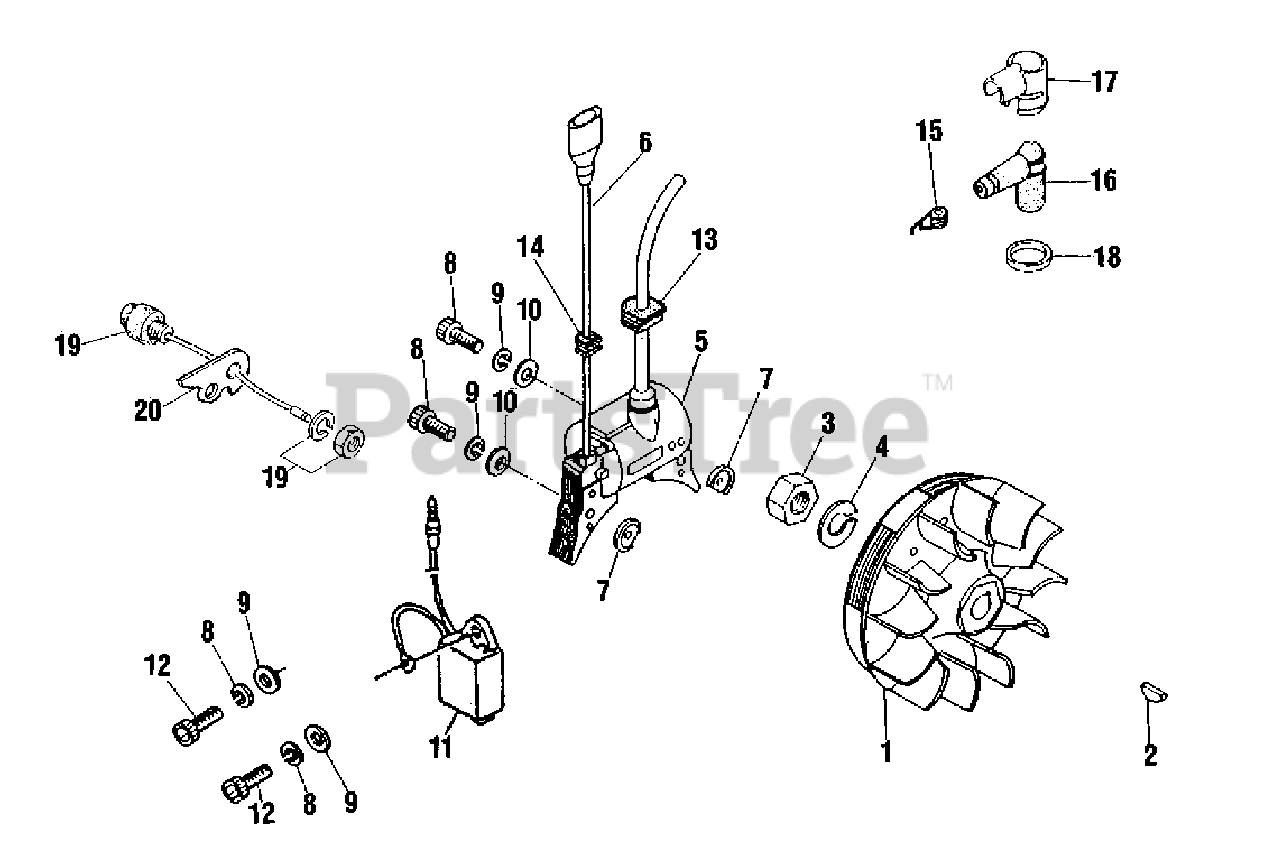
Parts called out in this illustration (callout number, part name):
1	FLYWHEEL
2	KEY, WOODRUFF - 3×10
3	NUT 10×1.25
4	WASHER, SPRING 10
5	IGNITION COIL ASSY
6	WIRE
7	COLLAR 4
8	BOLT
9	WASHER, SPRING 4 MM
10	WASHER 4.3×9.6×0.8
11	ELECTRONIC UNIT
12	BOLT M4×12
13	GROMMET
14	GROMMET, LEAD
15	TERMINAL, SPARK PLUG
16	CAP, SPARK PLUG
17	COVER, CAP
18	SEAL, SPARK PLUG
19	SWITCH, ON-OFF
